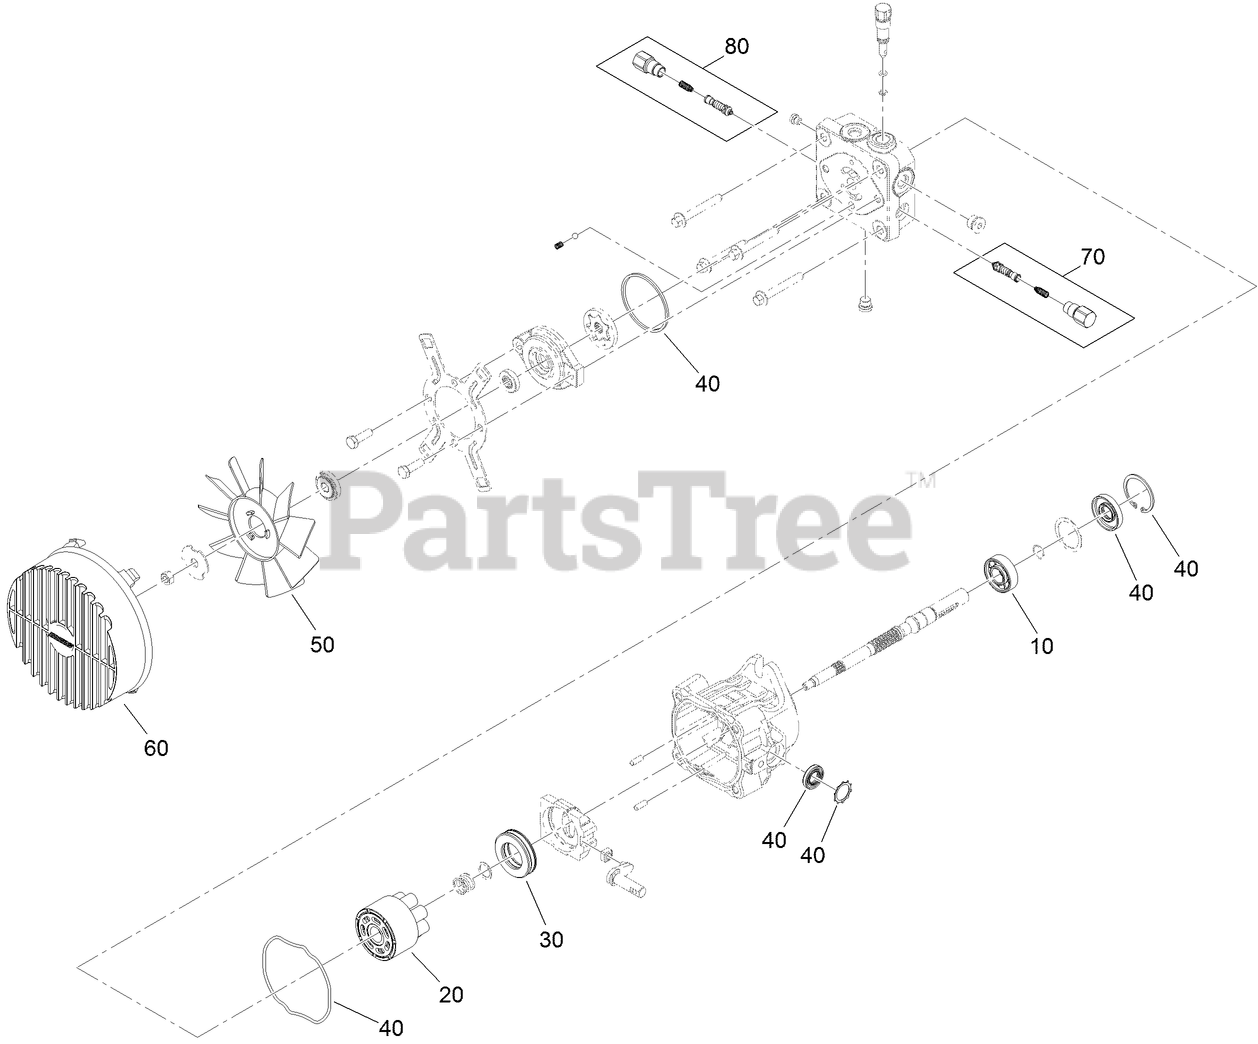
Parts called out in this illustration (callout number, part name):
10	BEARING-BALL
20	CYLINDER BLOCK KIT
30	BEARING-THRUST
40	SEAL OVERHAUL KIT
50	PUMP-COOLING
60	GUARD-PUMP
70	VALVE-SHOCK
80	SHOCK VALVE KIT
